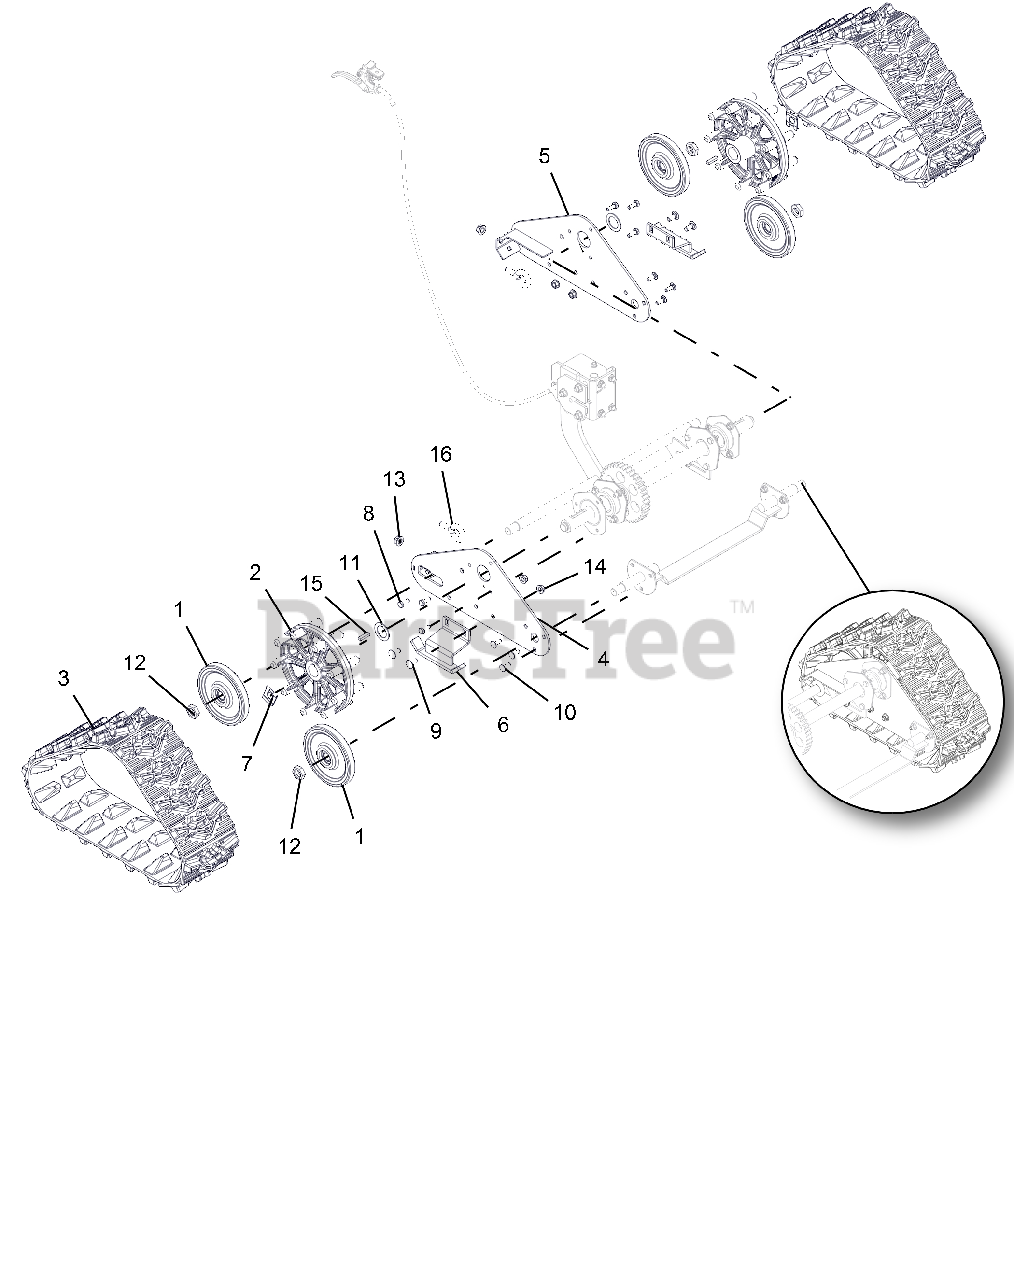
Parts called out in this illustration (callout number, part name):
1	WHEEL, BOGIE - SINGLE BEARING
2	WHEEL, MACHINED DRIVE
3	TRACK, RUBBER COMPACT
4	SIDE PLATE, RH COMPACT BLACK
5	SIDE PLATE, LH-COMPACT TRACK B
6	RUNNER, GUIDE-CMPT TRACK BLACK
7	CLIP, SNAP .625 DIA
8	@BLT-HEX .25-20X.75 GR5 YWZC
9	@BLT-RDHDSQNK .31-18X.75 G5YZ
10	@BLT-RDHDSQNK .25-20X.75 G5YZ
11	WSHR-FL-STL 1.010X1.505X.062YZ
12	@NUT-LK-NYL .625-18 YWZC
13	NUT-LK-CTR-FLG .38-16 YWZC
14	@NUT-LK-TOP-FLG .31-18 YWZC
15	KEY-RECT .25X.188X1.00
16	BLT-EYE .375-16X.880 YWZC
